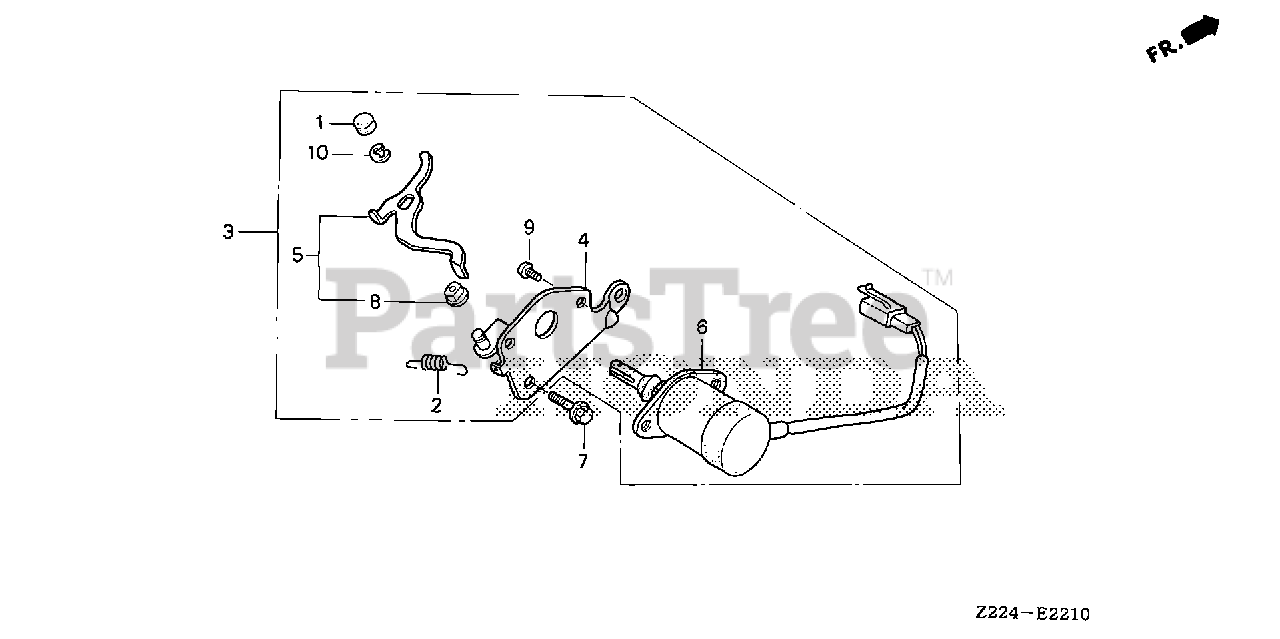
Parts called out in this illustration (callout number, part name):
1	CAP, CHOKE LEVER
2	SPRING, CHOKE RETURN
3	AUTO-THROTTLE ASSY.
4	STAY, SOLENOID THROTTLE
5	LEVER, SOLENOID THROTTLE
6	SOLENOID ASSY.
7	BOLT, FLANGE (6X12) (CT200)
8	BUSH, AUTO-THROTTLE LEVER
9	SCREW, PAN (5X8)
10	E-RING (4MM)
